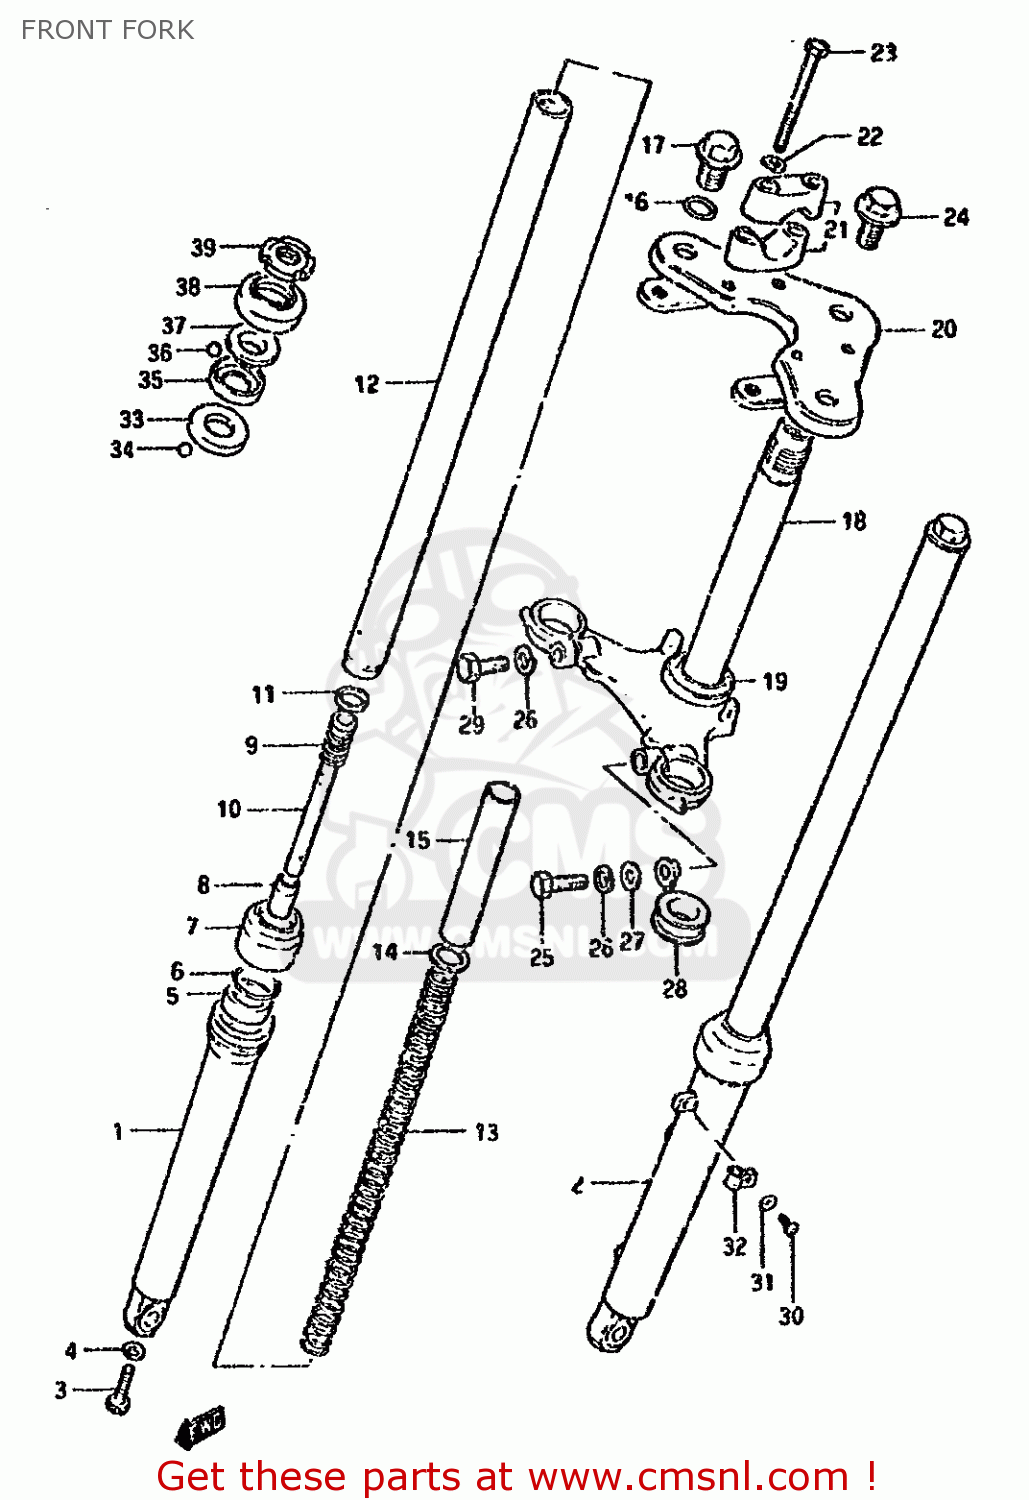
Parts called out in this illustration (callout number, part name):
1	TUBE,OUTER,RIGHT
2	TUBE,OUTER,LEFT
3	BOLT(8X27)
4	GASKET (NAS)
5	SEAL,OIL
6	RING,OIL SEAL STOPPER
7	DUST SEAL
8	PIECE,OIL LOCK
9	SPRING,REBOUND
10	CYLINDER,FR FORK
11	RING,PISTON
12	TUBE,INNER
13	SPRING
14	JOINT,SPRING
15	SPACER,SPRING
16	O-RING,FORK INNER TUBE
17	CAP
18	STEM,STEERING
19	RACE,STEERING OUTER LWR
20	HEAD,STEERING STEM
21	HOLDER,HANDLEBAR
22	WASHER,LOCK
23	BOLT
24	BOLT
25	BOLT,M10X1.25X
26	WASHER,LOCK
27	WASHER
28	CLIP
29	BOLT 10X30
30	SCREW
31	WASHER,LOCK 4M
32	CLIP,CABLE
33	LACE,STEERING INNER LWR
34	BALL
35	RACE,STEERING INNER UPR
36	BALL
37	RACE,STEERING OUTER UPR
38	DUST SEAL,STEERING UPR
39	NUT,STEERING STEM(25X44X10)
